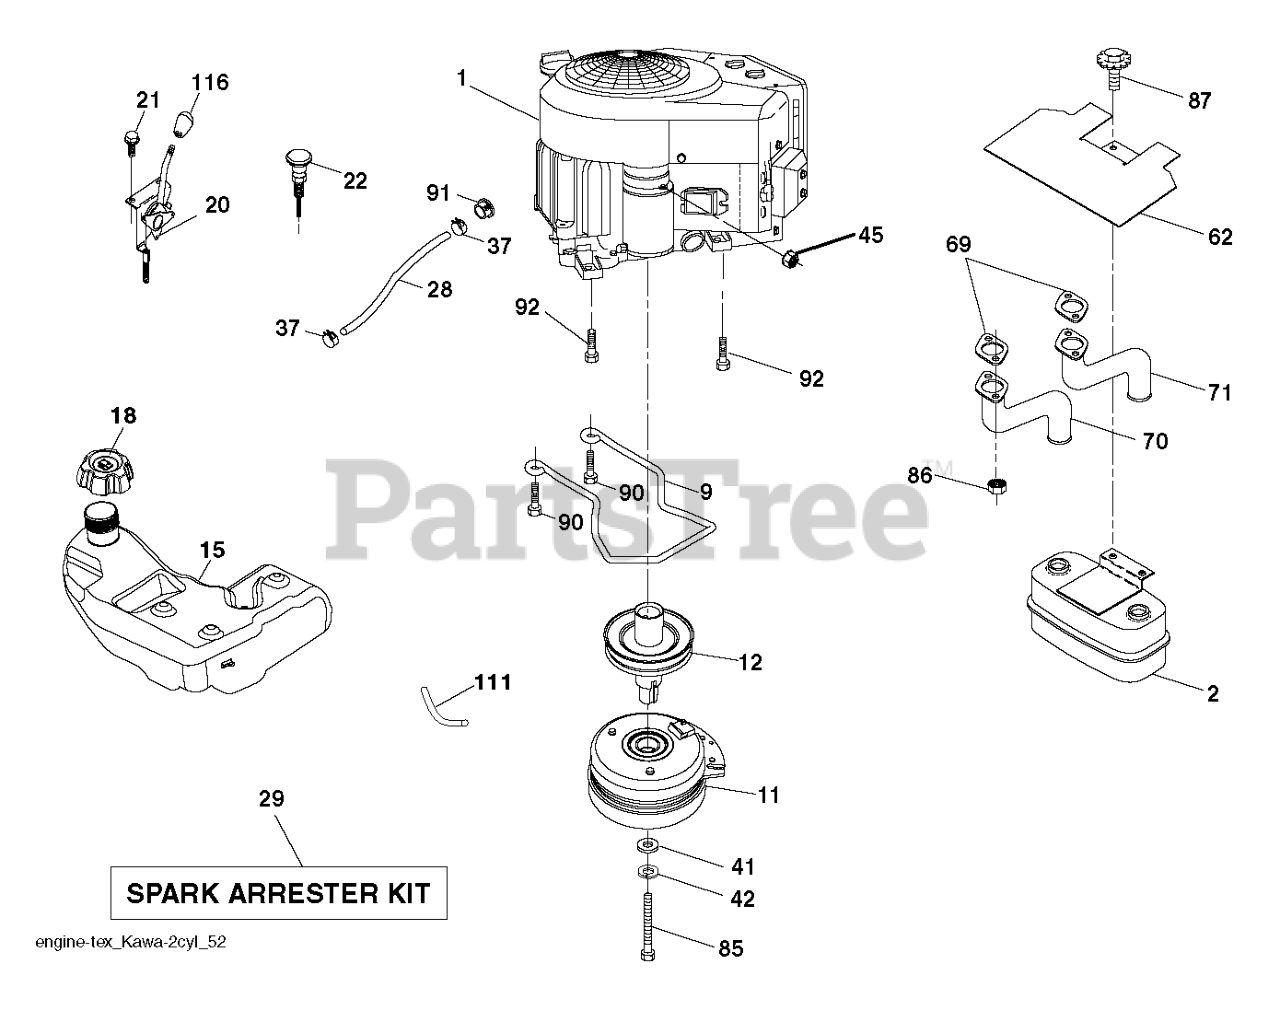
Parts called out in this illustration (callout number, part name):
2	MUFFLER.ASM.TWN.EXTNDED.DFLCTR
9	KEEPER.BELT.ENG.4.25"2.BLT.431
11	CLUTCH. 5.0 PD. 2.5 OFFSET
12	PULLEY.EXTENDED.SHAFT.GROUND
15	TANK.ASM.FUEL.3GA.CARB
18	CAP ASSY FUEL 3" GRAY
20	CONTROL.THROTTLE.PRO.
21	SCREW.#10 X 0.750.BOS
22	CONTROL, CHOKE
28	LINE.FUEL.64"REAR.EMIS
29	KIT.SPARK ARRESTOR 794945 B&S
37	HOSE CLAMP
42	LOCKWASHER
45	NUT
62	SHIELD.HEAT.MUFFLER
70	TUBE.EXHAUST.LH.FR961/FR730
71	TUBE.EXHAUST.RH.FR961/FR730
85	BOLT.HEX.7/16-20 X 5
86	NUT.HEX.FLANGE.TOPLOCK
87	SCREW
90	SCREW 3/8-16X1
91	BUSHING.1.375OD
92	SCREW 3/8-16X1
111	RP PURGE LINE
116	KNOB - SHIFT
